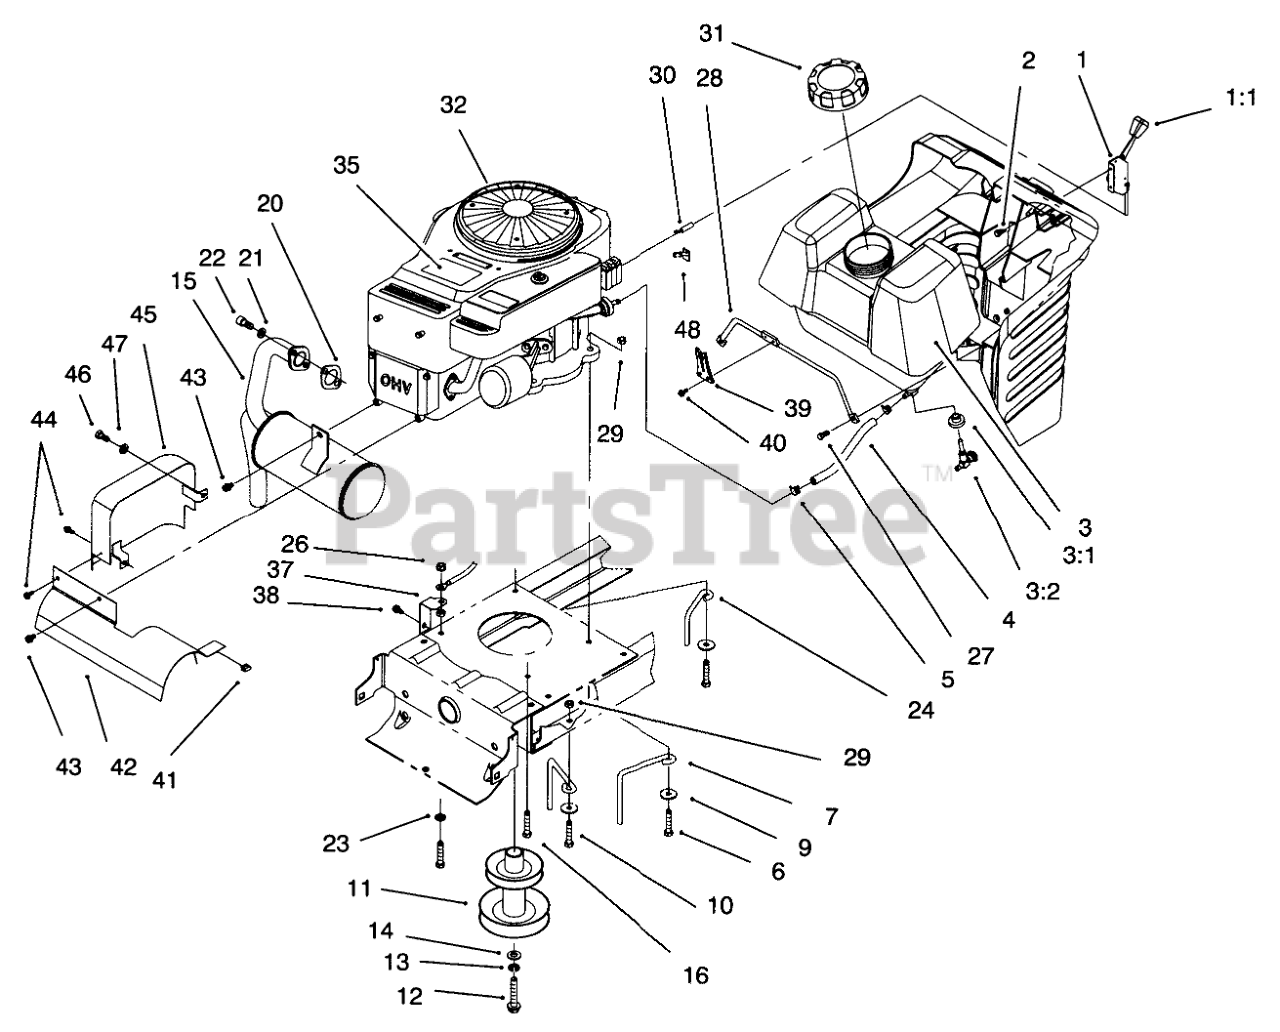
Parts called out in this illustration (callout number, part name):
1	Throttle Control ASM (Incl. Ref. #1:1)
2	SCREW-SPECIAL
3	Gas Tank Assembly (Incl. Ref. #3:1 & 3:2)
3:1	BUSHING
3:2	VALVE-FUEL
4	HOSE-FUEL
5	CLAMP-HOSE
6	SCREW-HH
7	GUIDE-BELT, ENGINE
9	WASHER-PIVOT
10	SCREW-HH
11	ENGINE PULLEY
12	SCREW-HH
13	WASHER-LOCK
14	WASHER-FLAT
15	MUFFLER-EXHAUST
16	SCREW-HWH, TAPTITE
20	GASKET-EXHAUST
21	WASHER-LOCK
22	SCREW-HSH
23	WASHER-LOCK
24	GUIDE-BELT, RH
26	NUT-KEPS
27	SCREW-SPECIAL
28	ROD-TANK, GAS
29	NUT-LOCK, NI
30	THROTTLE CABLE ASM
31	GAS CAP ASM
32	Engine-14.5hp B&s Ohv D+ (Only On: 71193)
32	Engine-14.5hp Ohv Tq+ (Only On: 71217)
35	DECAL - ENGINE
37	BRACKET-GROUND
38	SCREW-HWH
39	LATCH-HOOD
40	SCREW-HWH
41	CLIP-TINNERMAN
42	SHIELD-MUFFLER
43	SCREW-HWH
44	SCREW-HWHTF
45	HEAT SHIELD ASM
46	SCREW-HH
47	WASHER-LOCK
48	Reducer-Throttle Rpm (Only On: 71217)
